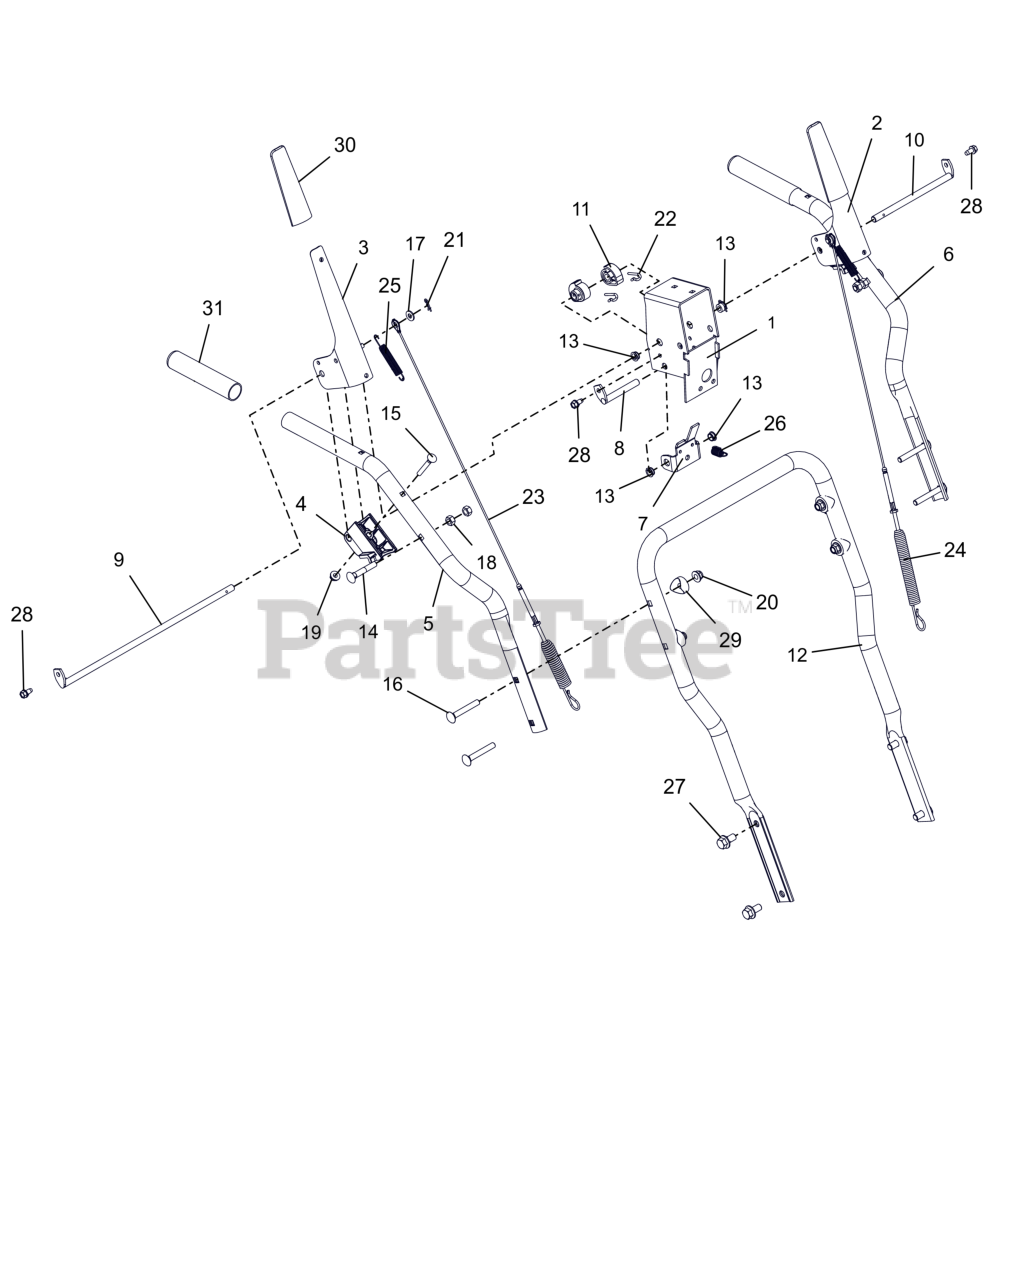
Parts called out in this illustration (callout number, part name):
1	WELDMENT, BRACKET INTERLOCK
2	LEVER, CLUTCH-LH
3	LEVER, CLUTCH-RH
4	BLOCK, CLUTCH PADDLE
5	HANDLEBAR, UPPER - RH
6	HANDLEBAR, UPPER - LH
7	BRACKET, INTERLOCK ARM
8	ROD, PIVOT - INTERLOCK
9	ROD, PADDLE MOUNT - LONG
10	ROD, PADDLE MOUNT - SHORT
11	CAM, INTERLOCK
12	HANDLEBAR, LOWER
13	BUSHING, POLYLINER-.38 SNAPIN
14	BLT-RDHDXLSQNK .31-18X2.0 G5YZ
15	BLT-RDHDXLSQNK .25-20X2.0 G5YZ
16	BLT, RHSN .31-18X2.25 G5 ZCC
17	WSHR,FLT .281X.625X.065 ZCC
18	NUT,LK-CTR .31-18 GA ZCC
19	NUT-LK-TOP-FLG .250-20 GF ZCC
20	NUT,LK-NYL-FLG .31-18 G5ZC120
21	PIN, HAIR #178 .06X.77 ZCC
22	PIN, SPRING CLIP
23	CABLE, AUGER (DELUXE & PRO)
24	CABLE, UPPER TRACTION
25	SPRING, EXTENSION
26	SPRING-EXT .047X.438X1.45
28	SCR-TAP .25-20X.50 HWH ZCC
29	SPACER, HANDLEBAR
30	SLEEVE, CLUTCH PADDLE-GRAY
31	GRIP,HANDLE-GRAY
